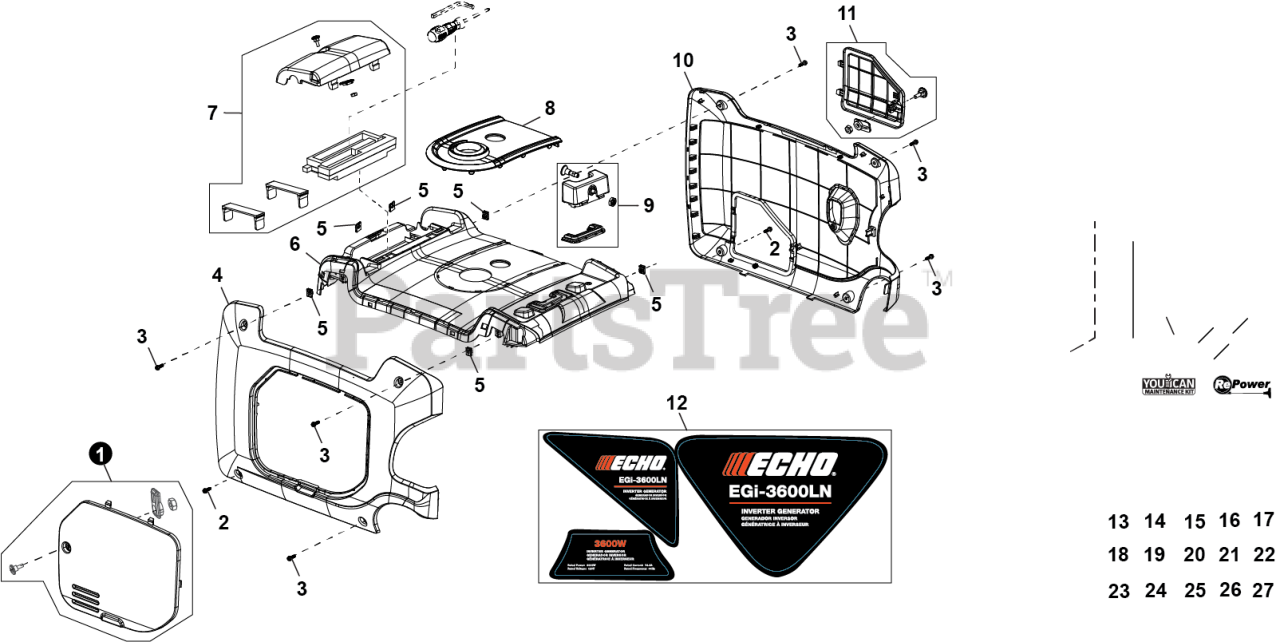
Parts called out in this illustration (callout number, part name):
1	ASSY., LEFT MAINTENANCE DOOR
4	PANEL, LEFT HOUSING
6	COVER, UPPER
7	ASSY., COVER
8	COVER, SPILL
9	ASSY., COVER
10	PANEL, RIGHT HOUSING
11	ASSY., RIGHT MAINTENANCE DOOR
12	SET, EGI-3600LN LABEL
